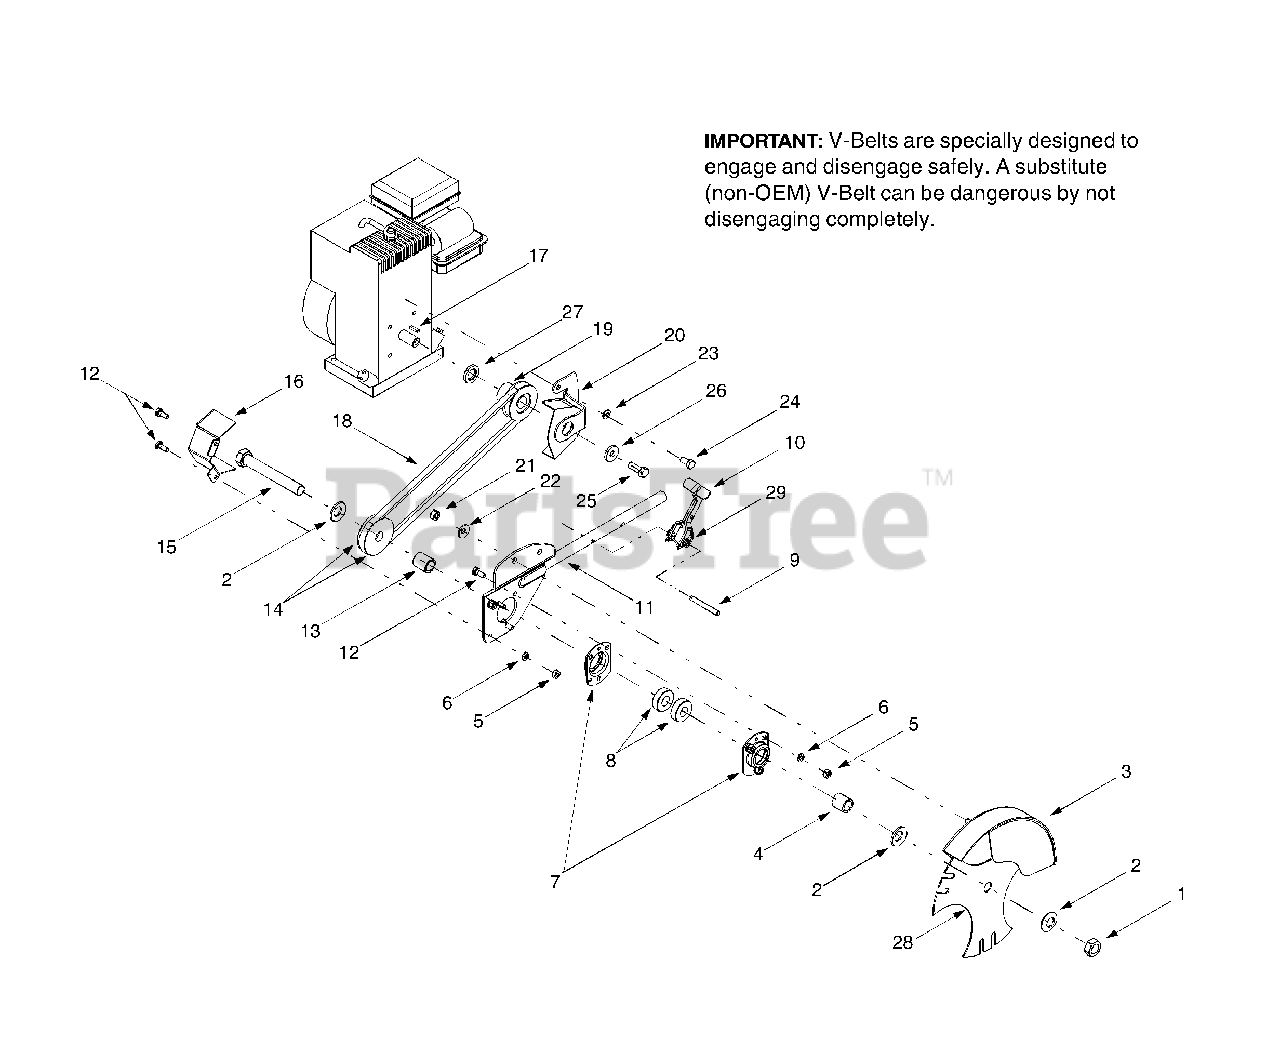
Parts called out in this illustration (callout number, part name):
1	Hex Jam Nut, 5/8-18
2	Bell Washer, .64 x 1.25 x .18
5	Hex Nut, 1/4-20
6	Lock Washer, 1/4
7	Bearing Housing
8	Ball Bearing, .62 x 1.38 x .44
9	Spirol Pin, 1/4 x 2.0
10	Adjustment Lever Assembly
13	Spacer, .635 x .88 x 1.03
14	Sheave, .6255 x .6295
15	Hex Cap Screw, 5/8-18 x 4.5
16	Spindle Belt Guard
17	Square Key, 3/16 x .75
18	V-Belt, 3/8
19	Engine Pulley, 3/8 x .75 x 2.38
22	Belleville Washer, .340 x .872
23	Lock Washer, 5/16
24	Hex Cap Screw, 5/16-24 x .625
25	Hex Cap Screw, 3/8-24 x 1.0
26	Flat Washer, .385 x 1.0 x .135
27	Spacer, .753 x 1.25 x .175
29	Double Torsion Spring
